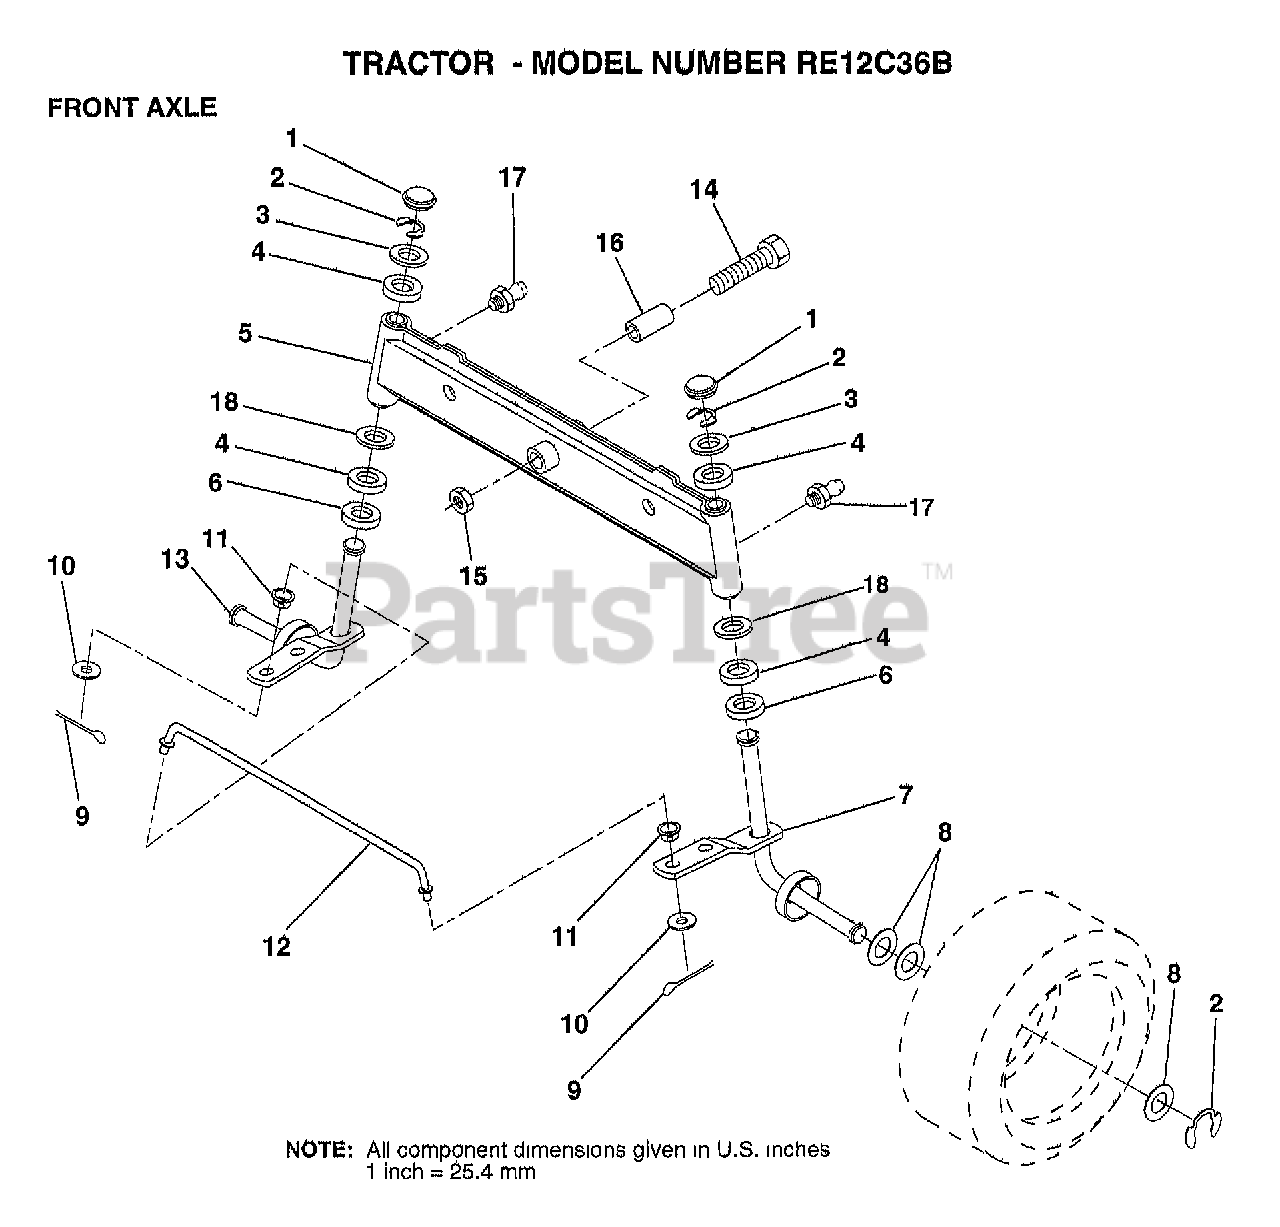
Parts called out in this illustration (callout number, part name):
1	CAP
2	RING
3	WASHER
4	COL. SRTG. BEAR.
5	AXLE ASM FRONT
6	WASHER .T
7	SPINDLE.ASSY.RH
8	WASHER
9	COTTER PIN
10	WASHER
11	BUSHING.DRAGLINK
12	TIE ROD
13	SPINDLE.ASSY.LH
14	BOLT HEX 5/8-11
15	"NUT-LOC,FLANGE LT"
16	BEARING
17	ZERK M
18	WASHER
